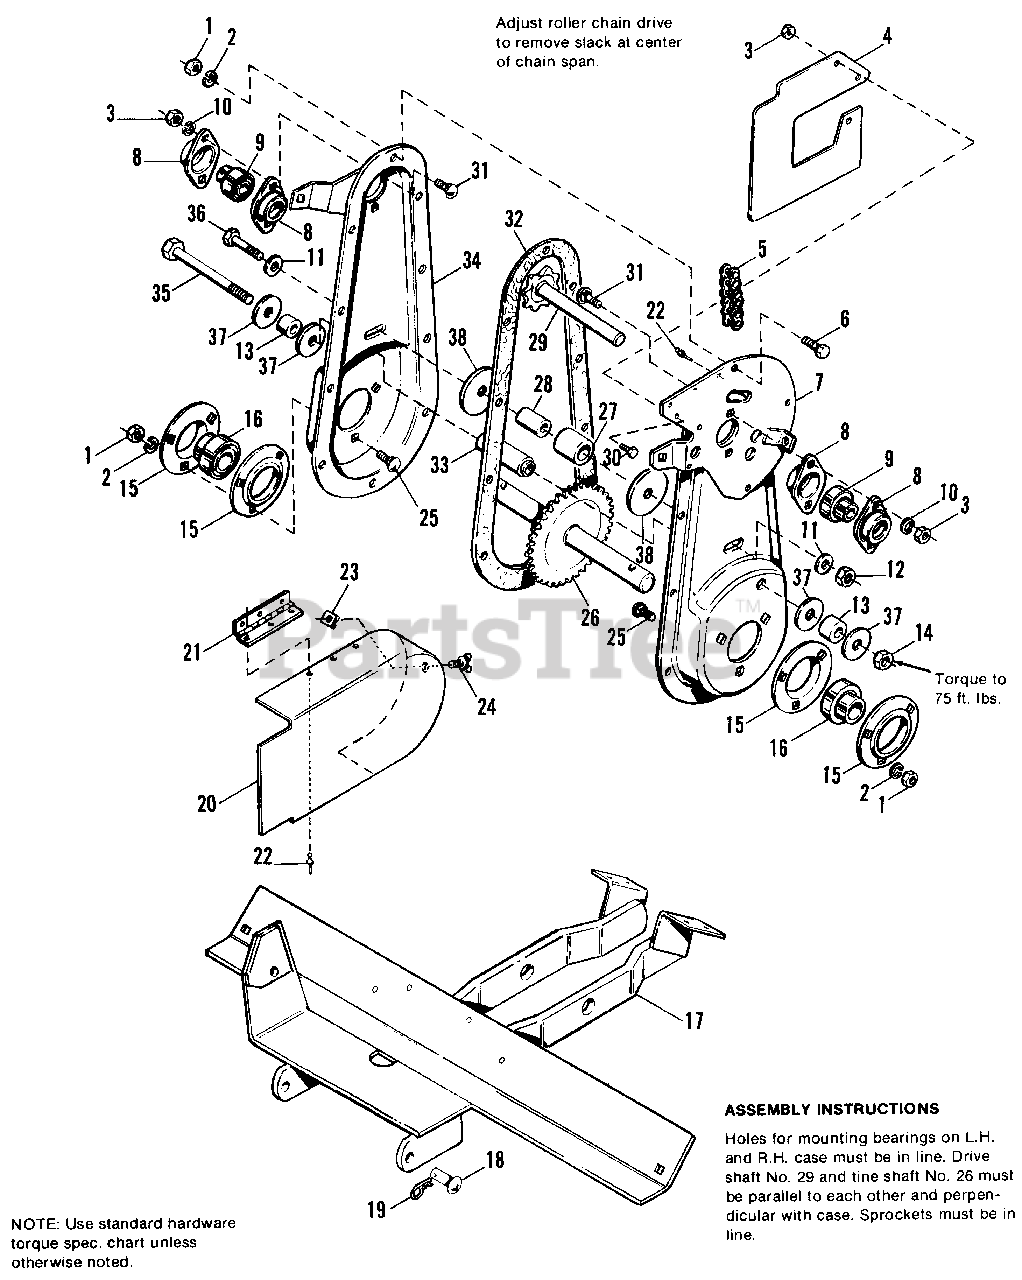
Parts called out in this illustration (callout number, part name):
1	NUT, Hex, Full, 5/16-18
2	LOCKWASHER, 5/16
3	NUT, Hex, Full 1/4-20
4	COVER, Guard
6	CAPSCREW, Hex Hd., 5/16-18 x 5/8
7	CASE ASSY., Half, L.H.
10	WASHER, Lock, 1/4
11	WASHER, Special
12	NUT, Hex Hd., Full, Lock, 3/8-16
14	NUT, Hex Hd., Full, Lock, 1/2-13
15	FLANGE, Bearing
16	BEARING, Cartridge
17	FRAME & HITCH ASSY.
19	CLIP, Hairpin
20	GUARD, Belt
23	NUT, "U" Type
24	SCREW, Wing
25	CARRIAGE BOLT, 5/16-18 x 3/4
26	SHAFT ASSY., Tine
29	SHAFT ASSY., Drive
30	CAPSCREW, Hex Hd., 1/4-20 x 1/2
31	CARRIAGE BOLT, 1/4-20 x 3/4
32	GASKET, Case
33	SPACER, Case
34	CASE ASSY., Half R.H.
35	CAPSCREW, Hex Hd., 1/2-13 x 5
36	CAPSCREW, Hex Hd., 3/8-16 x 2-1/4
